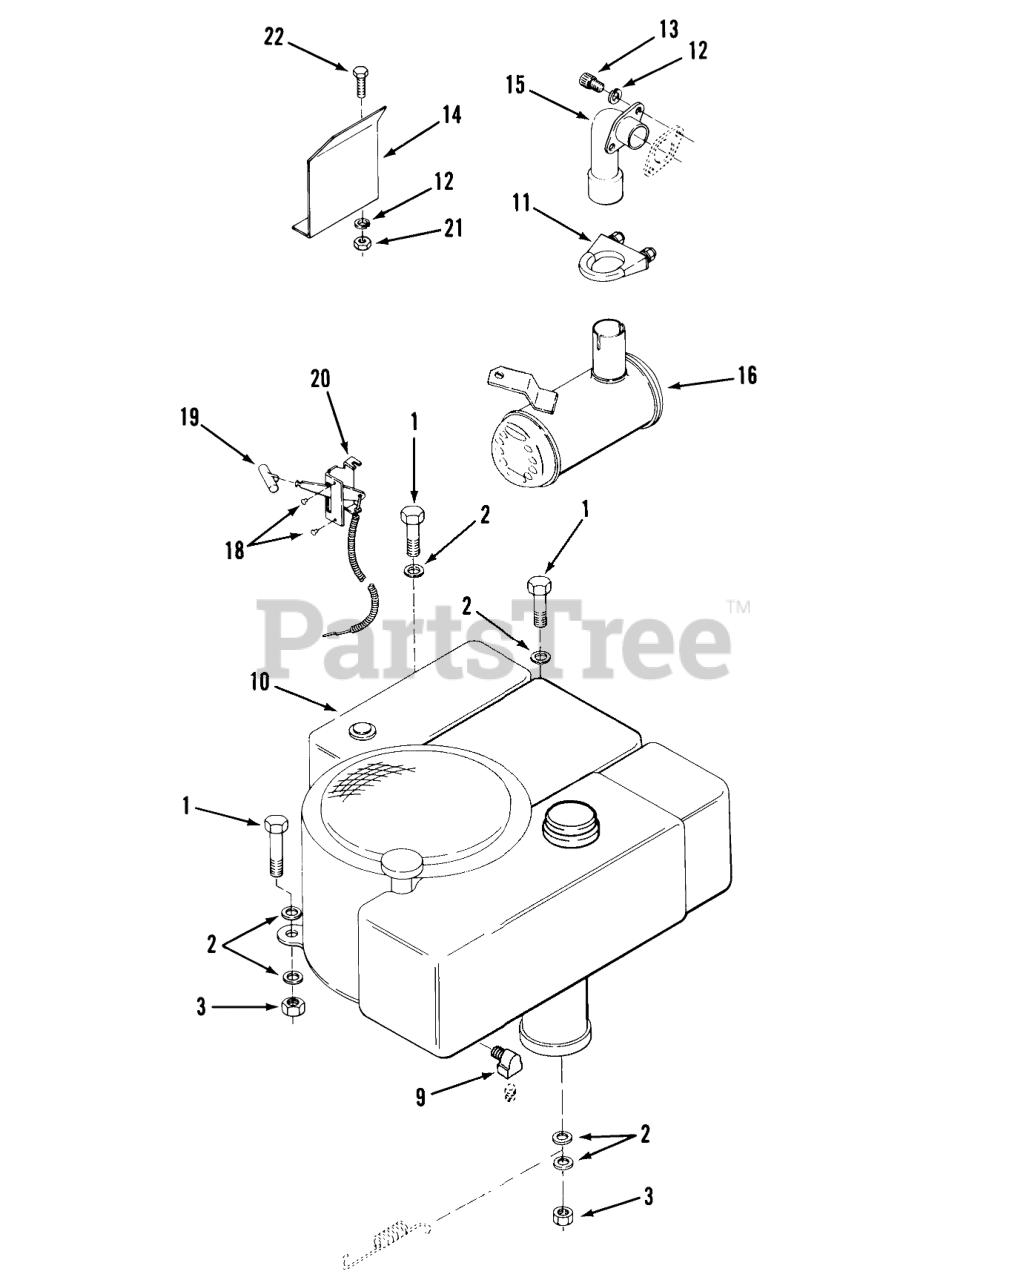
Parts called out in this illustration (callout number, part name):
1	Bolt
1	HHCS
2	WASHER 5/16 SAE
2	WASHER
3	Nut
9	ELBOW-STREET
10	Engine 8 H.P.-B&S Model 191707 Type 5821-01 A-81 Only
10	Engine 11 H.P.-B&S Model 252707 Type 0648-01 A-111 Only
11	CLAMP-1 1/2
12	Lockwasher
13	SHCS 5/16-18X.625
14	Deflector-Exhaust A-111 Only
15	Exhaust Manifold A-111 Only
16	MUFFLER
18	RIVET
19	KNOB-CONTROL
20	CONTROL-THROTTLE
21	Nut
22	H H C S
